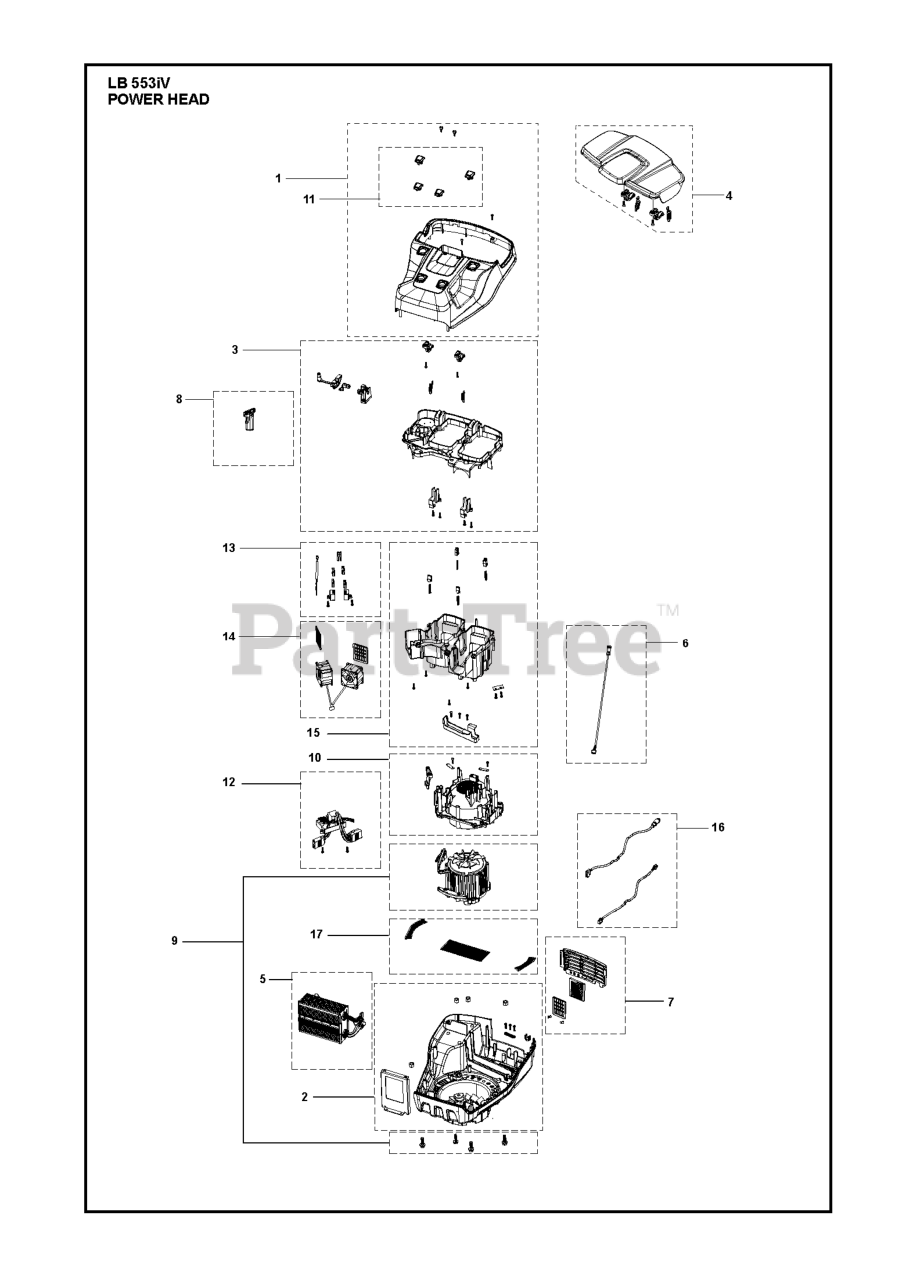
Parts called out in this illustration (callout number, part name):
3	Battery Box
13	Battery Box
14	Battery Box
15	Battery Box
